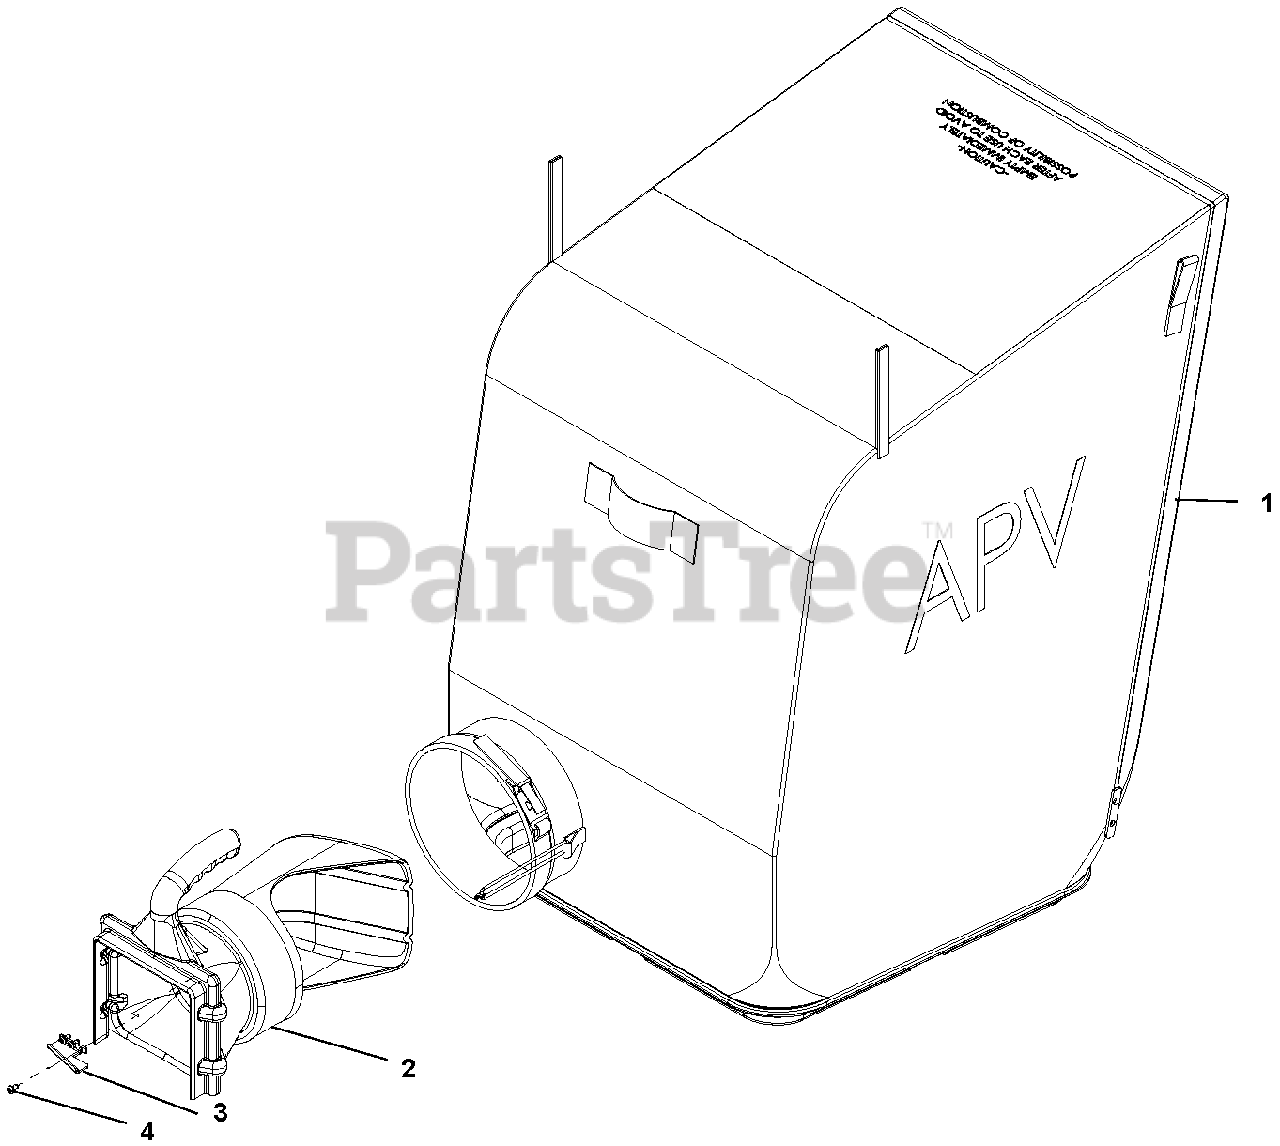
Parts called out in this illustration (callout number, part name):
1	Bag, APV, Black Poly Felt
2	APV Bag Discharge Chute, '07 Red
3	Switch Depression Bracket
4	Screw, Steel, B 10 x .37 NI
